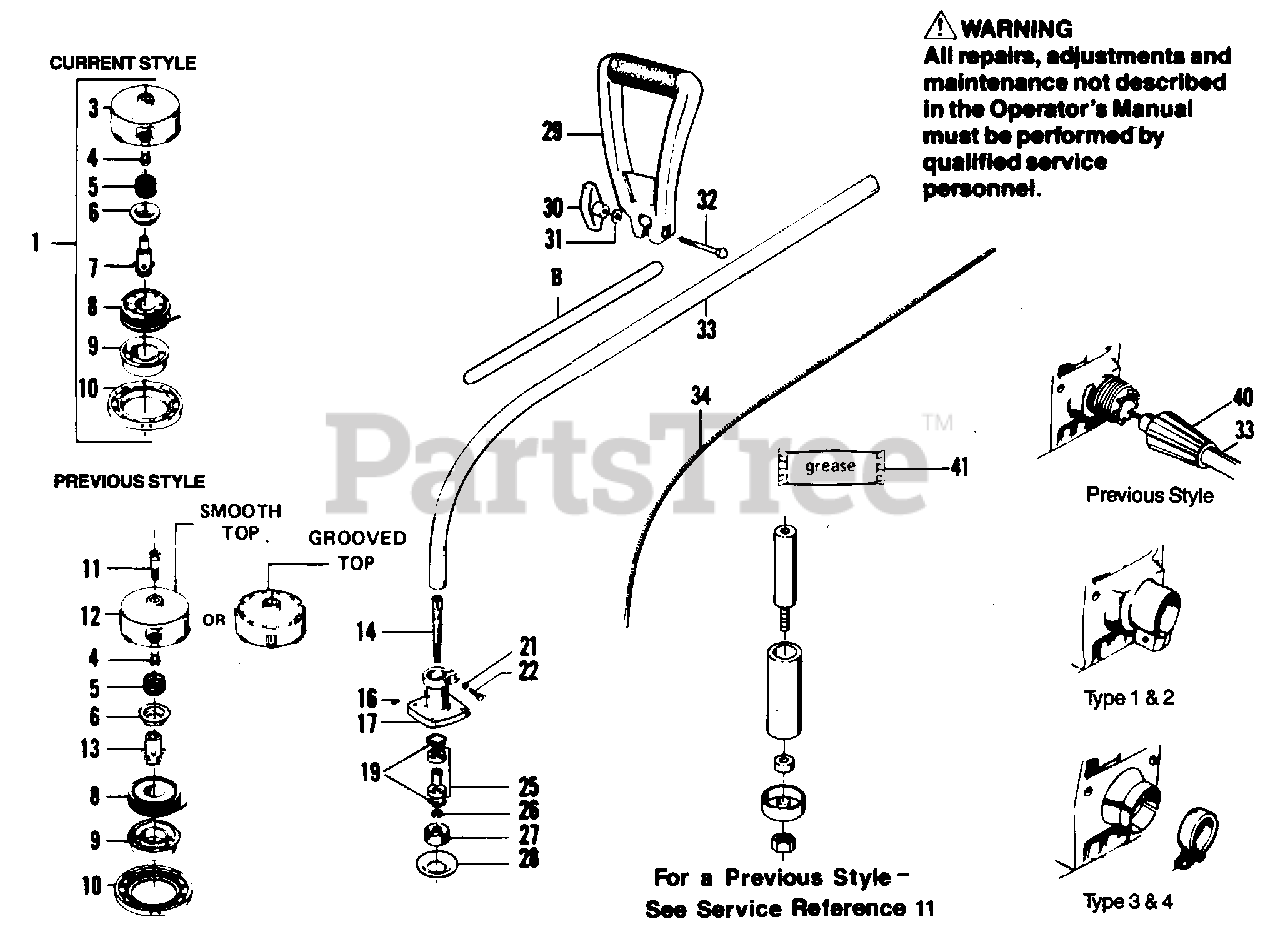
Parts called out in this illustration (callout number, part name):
1	Cutting Head Ass'y. - Current Style (Incl. #3-10)
3	Hub w/Line Saver - Current Style
4	Line Saver
5	Spring
6	Adaptor - Spring
7	Drive Gear - New Style
8	Spool w/Line
9	Release Button
11	Bolt - Drive Adaptor - Previous Style
12	Hub w/Line Saver - Previous Style See Service Reference 6.
13	Drive Gear - Previous Style
14	Shaft - Arbor - Type 1 Only
16	Screw - 5/16 - Self Tapping
17	Bearing Housing Ass'y - (Inc. #14,19, 21,22,25-27) Type 1 See Ser. Ref. 11
19	Retainer - Bearing
21	Washer - 1/4 Int. Tooth Lock - Type 1 Only
22	Screw - Pinch Clamp - Type 1 Only
25	Bearings & Spacer Kit - Type 1 Only
26	Washer - 3/8 - Dust Cup - Type 1 Only
27	Type 2, 3 & 4
29	Model XR-50
29	Model XR-70
30	Knob - 1/4 20 - Model XR-70
31	Washer - 1/4 Flat
32	Hex Bolt - 1/4 - 20x1 - 1/2
33	Drive Shaft Hsg., Previous Style (Incl. #40) Model XR-50
33	Drive Shaft Hsg., Previous Style (Incl. #40) Model XR-70
33	Drive Shaft Hsg., Previous Style (Incl. #40) Model XR-50 - Type 1
33	Drive Shaft Hsg., Previous Style (Incl. #40) Model XR-50 - Type 2
33	Drive Shaft Hsg., Previous Style (Incl. #40) Model XR-50 - Type 3 & 4
33	Drive Shaft Hsg., Previous Style (Incl. #40) Model XR-70 - Type 1
34	Model XR-50 - Type 1
34	Model XR-50 - Type 2, 3 & 4
34	Model XR-70
40	Collar Nut Collar Nut Style (Incl. #40)
41	Flex Shaft Lube
B	Decal-Safety Label
